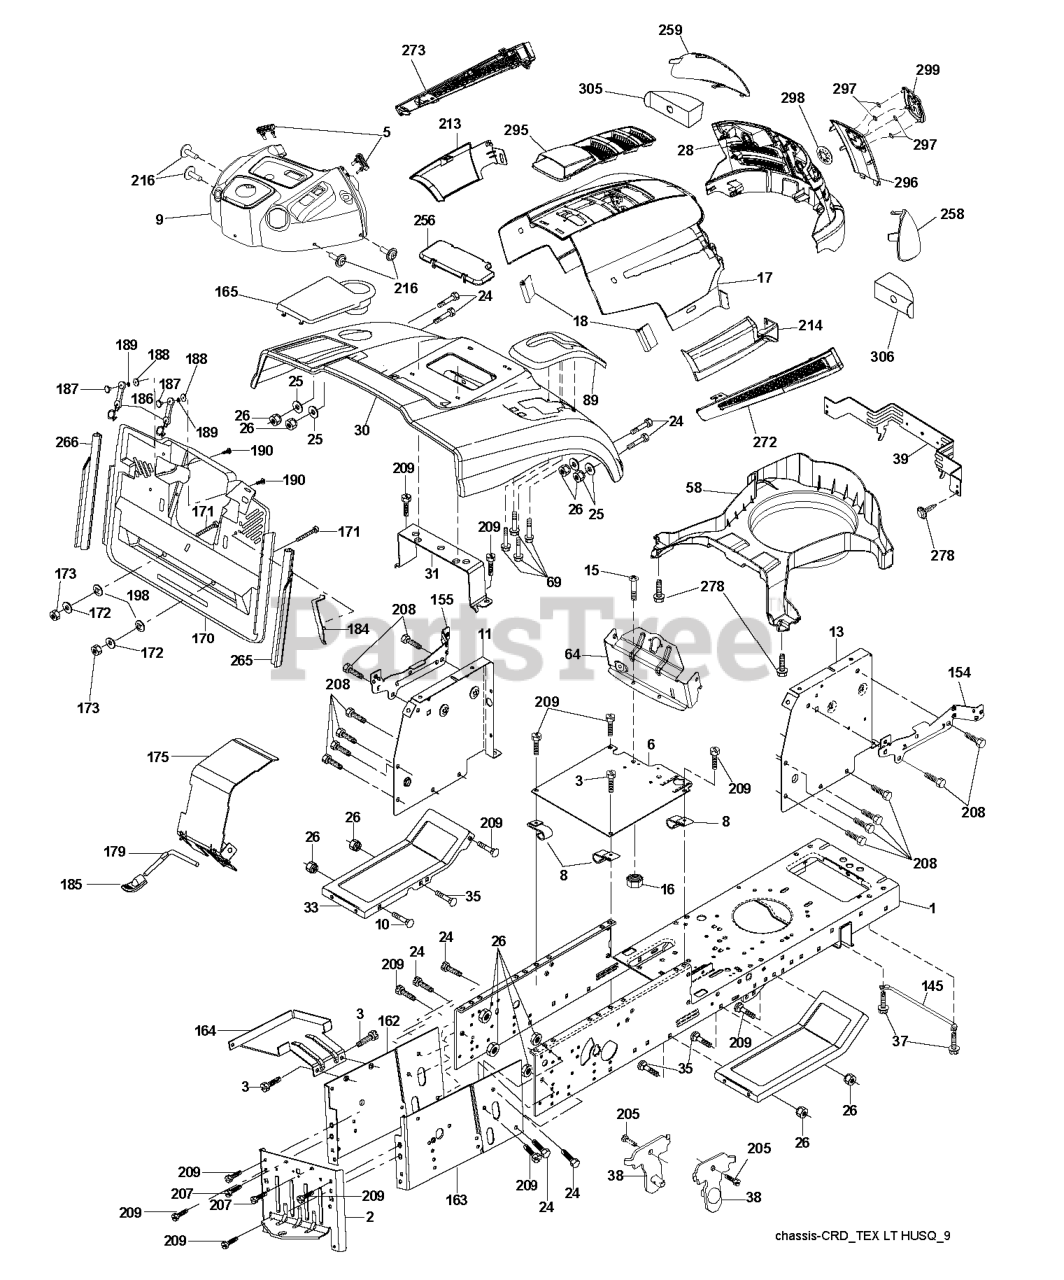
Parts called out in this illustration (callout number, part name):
2	DRAWBAR
3	SCREW 3/8-16X3/4
5	BUMPER DASH
6	PLATE
8	CLIP,INSULATOR
10	BOLT D
11	PANEL.DASH.LH.LTX
13	PANEL ASM, DASH RH
15	Screw, Machine, Truss Head 5/16-18 UNC x 3/4
16	NUT
17	HOOD
18	BUMPER.HOOD.TEX.HUSQVARNA
25	WASHER
26	NUT
28	RP GRILLE/LENS ASM.
30	CONSOLE.CRD.AUTO.GRY
31	BRACKET SUPPORT FENDER
33	FOOTREST PNT LH
34	FOOTREST PNT RH
37	Screw 5/16-18 x 1/2 Hex, Self Tapping 5/16-18 x 1/2
38	BRACKET ASM PIVOT MOWER REAR
39	BRACKET PIVOT
69	SCREW.HI-LO.CONSOLE
89	CONSOLE.CRD.AUTO.GREY.2005
145	ROD.PIVOT.HOOD
162	BRACKET
163	BRACKET EXTEN CHASSIS RH CRD
165	RP.COVER.BATTERY.CRD.GREY
172	WASHER
175	DOOR TRAP
179	ROD PIVOT FBI
184	BRACKET.ACTUATOR.BAGGER.SRD
186	LATCH ASSY
187	WELDNUT
189	LOCKWASHER #10
190	SCREW
207	SCREW, 5/16-18 X 1/2
208	SCREW 3/8-16X1/2
209	SCREW, 3/8-16X3/4
213	SKIRT SIDE LH
214	SKIRT SIDE RH
216	SCREW HEXWSHR 1/4-20X3/4
256	COVER FENDER CRD
258	LENS.HUSQVARNA LT.RH
259	LENS.HUSQVARNA LT.LH
265	SEALING
266	SEALING
272	VENT SIDE HOOD RH
273	VENT SIDE HOOD LH
278	SCREW.#10 X 0.750.BOS
295	VENT TOP HOOD
296	TRIM
297	CLIP.RETAINER.TINNER.
298	NUT PUSH M
299	RP LOGO
305	INSERT REFLECTIVE
306	INSERT.REFLECTIVE.RH.
